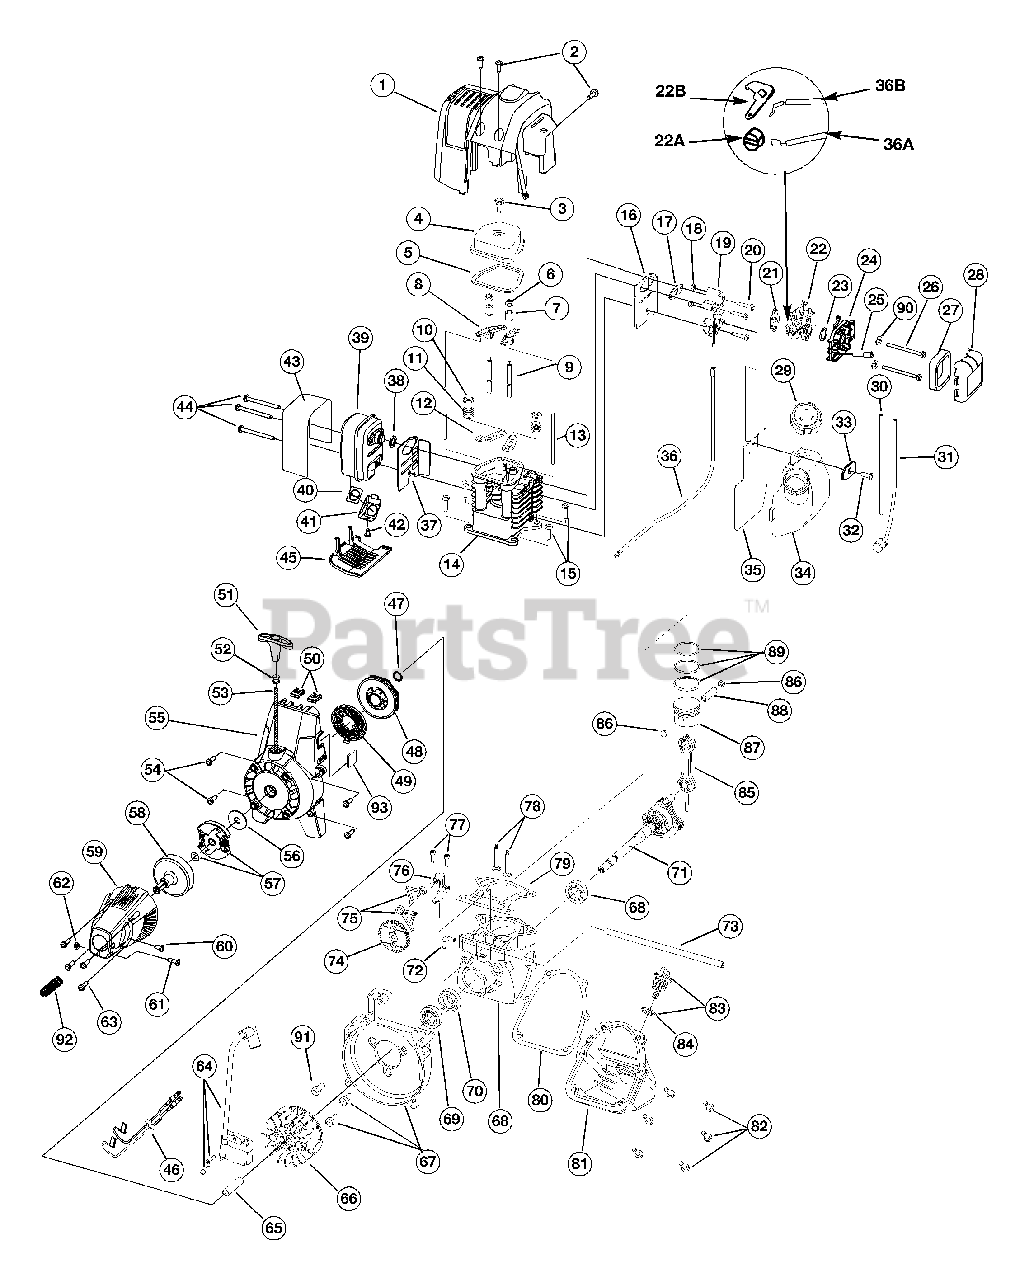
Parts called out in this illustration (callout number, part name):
1	Engine Cover
2	Engine Cover Screws
3	Valve Cover Screw
4	Valve Cover
5	Valve Cover Gasket
6	Rocker Adjustment Nut
7	Rocker Arm Pivot
9	Rocker Arm Stud
10	Valve Spring Retainer
11	Valve Spring
12	Push Rod Guide
13	Push Rod
14	Cylinder Head
15	Cylinder Screw
16	Intake Baffle
17	Carburetor Mount Gasket
18	Nut
19	Carburetor Mount
20	Carburetor Mount Screw
21	Carburetor Gasket
22A	Carburetor with Primer
22B	Carburetor with Primer
23	O-Ring, Carburetor
24	Air Filter/Choke Cover Assembly
25	Breather Tube
26	Air Filter Mounting Screw
28	Air Filter Cover
30	Fuel Return Line
31	Fuel Pick-Up Line with Filter
34	Fuel Tank Assembly
35	Fuel Tank Shield
36A	Throttle Cable
36B	Throttle Cable
37	Muffler Baffle
38	Muffler Gasket
39	Muffler
40	Spark Arrestor Screen
41	Screen Cover
43	Muffler Shield
44	Muffler Mounting Screw
45	Muffler Cover
46	Switch Wire Assembly
47	Palnut
48	Recoil Pulley
49	Recoil Spring
51	Pull Handle
54	Starter Housing Screw
55	Starter Housing Assembly
56	Clutch Washer
57	Clutch with Spacer
58	Clutch Drum
59	Clutch Cover
60	Anti-Rotation Screw
61	Screw
63	Clutch Cover Screw
64	Ignition Module with Screws
66	Flywheel
67	Shroud Assembly with Screws
68	Crankcase Assembly
73	Breather Hose
75	Cam Follower Set
76	Cam Bracket
77	Cam Bracket Screw
78	Valves, Intake and Exhaust
79	Cylinder Gasket
80	Oil Pan Gasket
81	Oil Pan
82	Oil Pan Screw
83	Dipstick Assembly
85	Connecting Rod
86	Wrist Pin Button
87	Piston
89	Piston Ring Set
92	Compression Spring
